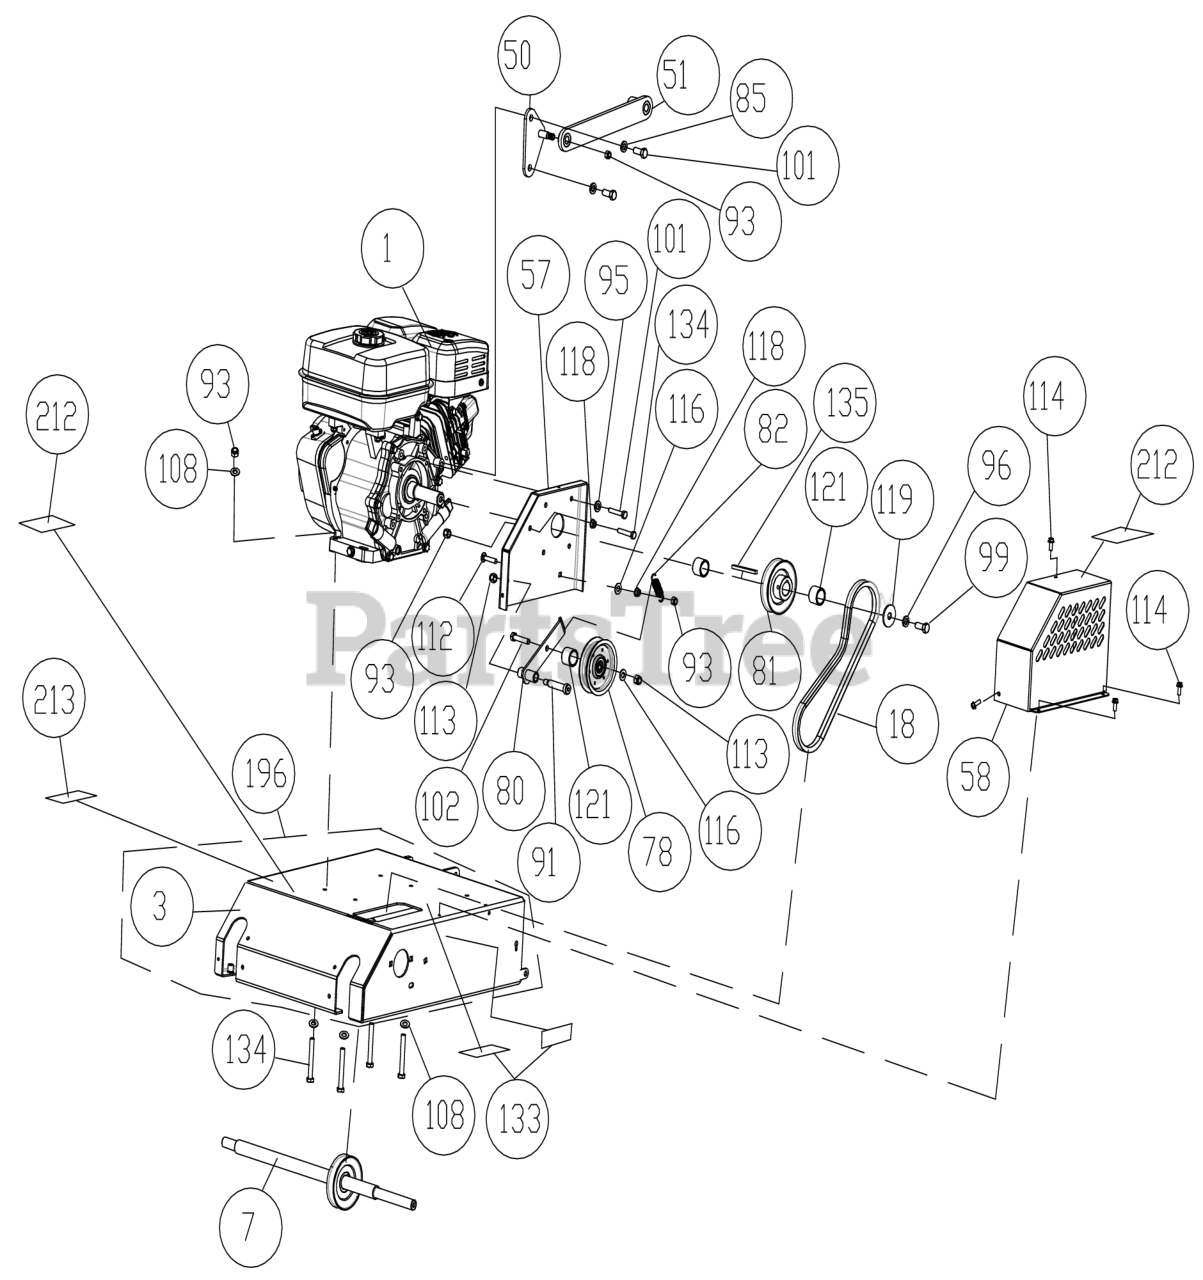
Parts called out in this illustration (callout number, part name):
1	ENGINE HONDA 9 OHV GX270
3	ENGINE BASE WA
7	JACKSHAFT WA
18	BELT 6932 POWERATED
50	ENGINE BRACKET WA OS901SP
51	LINKAGE, FOOT CONTROL WA OS901SP
57	BRACKET GUARD BELT UPPER ENGINE OS900SP
58	BELT GUARD UPPER WA OS900SP
78	PULLEY IDLER 4" OD X 3/8"
80	ARM IDLER WA UPPER OS900SP
81	SEE: 351289 (REMOVE SPACERS FROM 351296 TO INSTALL)
82	SPRING IDLER UPPER OS900SP
91	BOLT SHOULDER 1/2" X 2"
93	NUT LOCK 5/16"-18 HEX Z/P
95	WASHER LOCK 5/16 ST MED
96	WASHER LOCK 7/16" S/T MED
99	SCREWCAP 7/16-20 X 1" HCS GR. 8 W/PATCH
101	SCREWCAP 5/16"-24 X 1" GR.8 ZP W/PATCH
102	SCREWCAP 3/8"-16 X 1 3/4" HCS ZP
108	WASHER 5/16" FLATWASHER Z/P
112	BOLT CARRIAGE 5/16"-18X1 1/2" ZP
113	NUT LOCK 3/8"-16 HEX
114	SCREW SELF TAP 1/4"-20 X 5/8" HWH TYPE F
116	WASHER 3/8"SAE 13/32"X13/16"X1/16"
118	NUT FLANGE 5/16"-18 ZP
119	PLATE IMPELLER WASHER
121	SPACER 1.25" OD X 1.010" ID X 0.813" LNG
133	LABEL DANGER
134	SCREWCAP 5/16"-18X1 3/4" HCS ZP
135	KEY SQUARE 1/4" X 1"
196	ENGINE BASE WA OS901SP W/LABELS
212	LABEL, THD CLEANING FEE 2.00" X 4.00"
213	LABEL, HD TOOL RENTAL 2" X 4"
